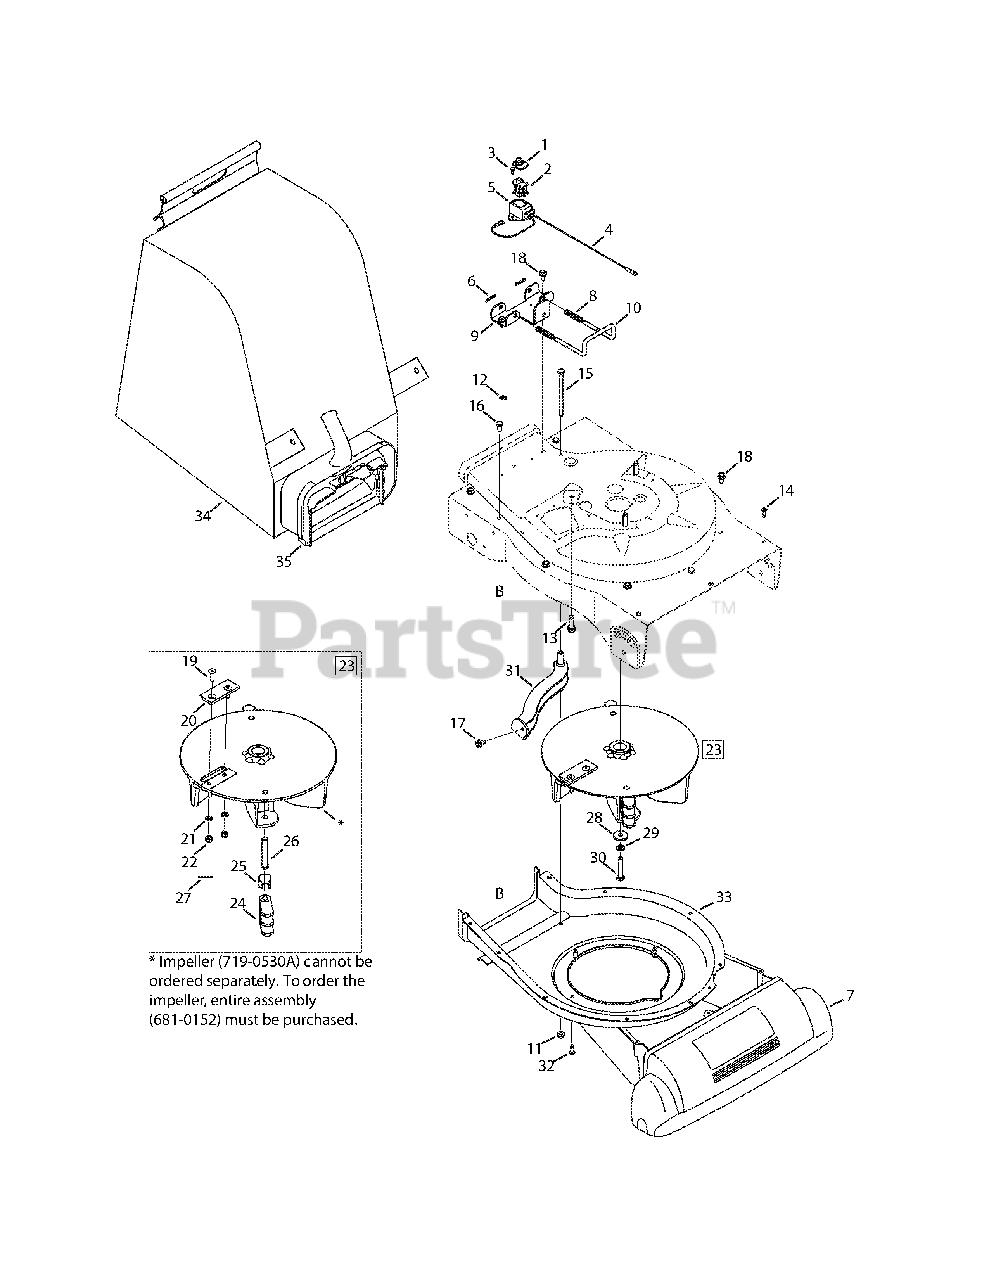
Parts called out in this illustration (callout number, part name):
1	Switch Cover
2	Safety Switch
3	Hex Washer Screw, #10-16 x.50
4	Wire Harness
5	Safety Switch Cover
6	Cotter Pin
7	Nozzle Cover
8	Compression Spring
9	Mounting Bracket
10	Lock Rod
11	Flange Lock Nut, 5/16-18
12	External Lock Washer 5/16
13	Hex Washer Screw 3/8-16 x 1.25
14	Screw, #12-16 x .750
15	Hex Cap Screw 5/16-18 x 4.5
16	Hex Cap Screw 5/16-18 x.625
17	Screw, 5/16-18 x.500
18	Screw, 5/16-12 x.75
19	Hex Screw 5/16-24 x 1.0
20	Chipper Blade
21	Lock Washer 5/16
22	Hex Lock Nut 5/16-24
23	Impeller Assembly
24	Flail Blade
25	Pin Clip
26	Clevis Pin
27	Spiral Pin
28	Flat Washer.375 ID x 1.25 OD
29	Lock Washer 3/8
30	Hex Cap Screw 3/8-24 x 2.0
31	Screen Assembly
32	Shoulder Screw, .30 x .46
34	Bag Assembly
35	Chute Assembly
